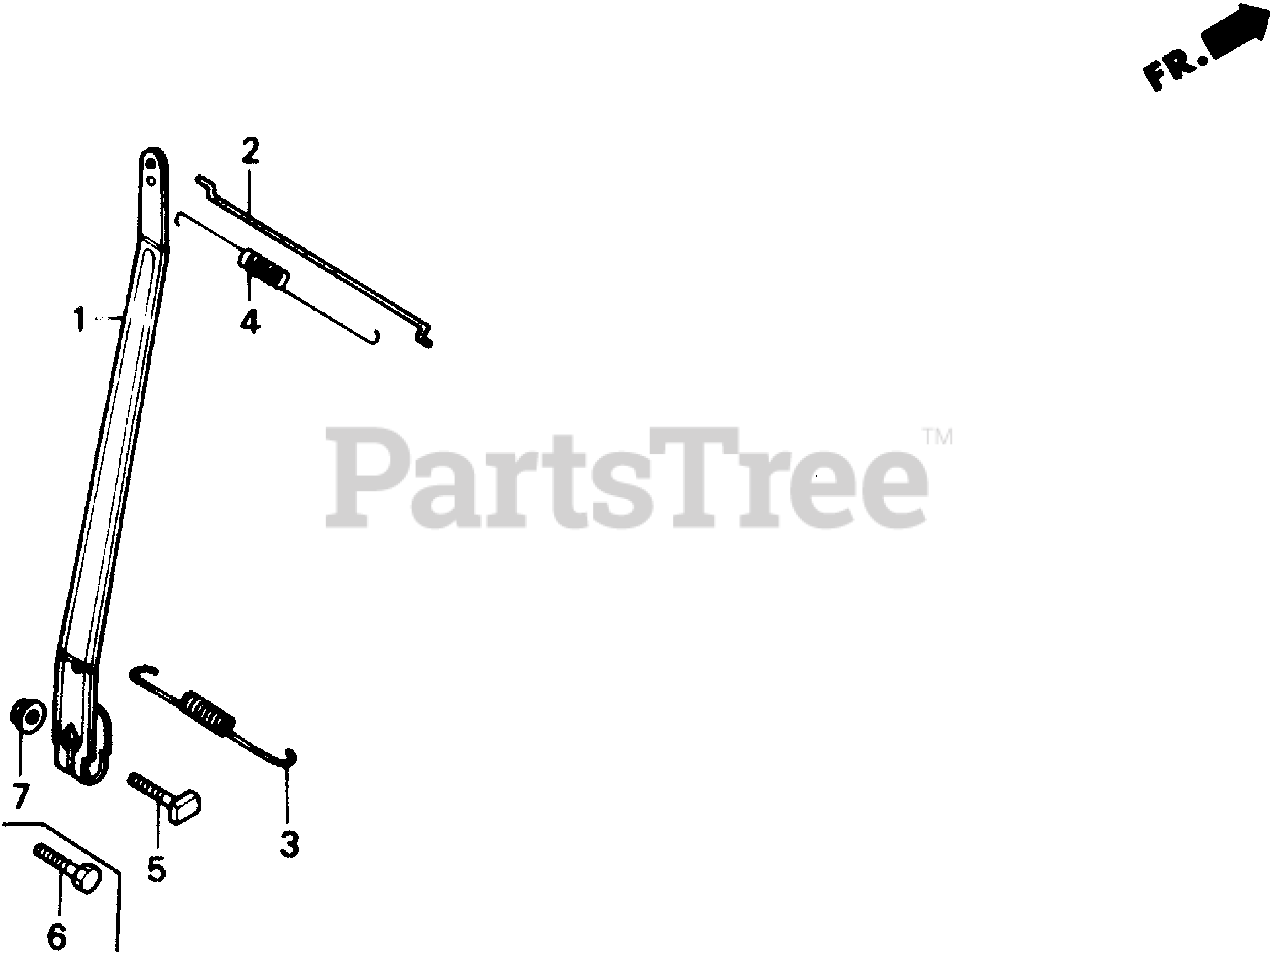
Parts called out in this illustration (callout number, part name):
1	ARM, GOVERNOR
2	ROD, GOVERNOR
3	SPRING, GOVERNOR
4	SPRING, THROTTLE RETURN
5	BOLT, GOVERNOR ARM
6	BOLT, HEX. (6X20)
7	NUT, FLANGE (6MM)
